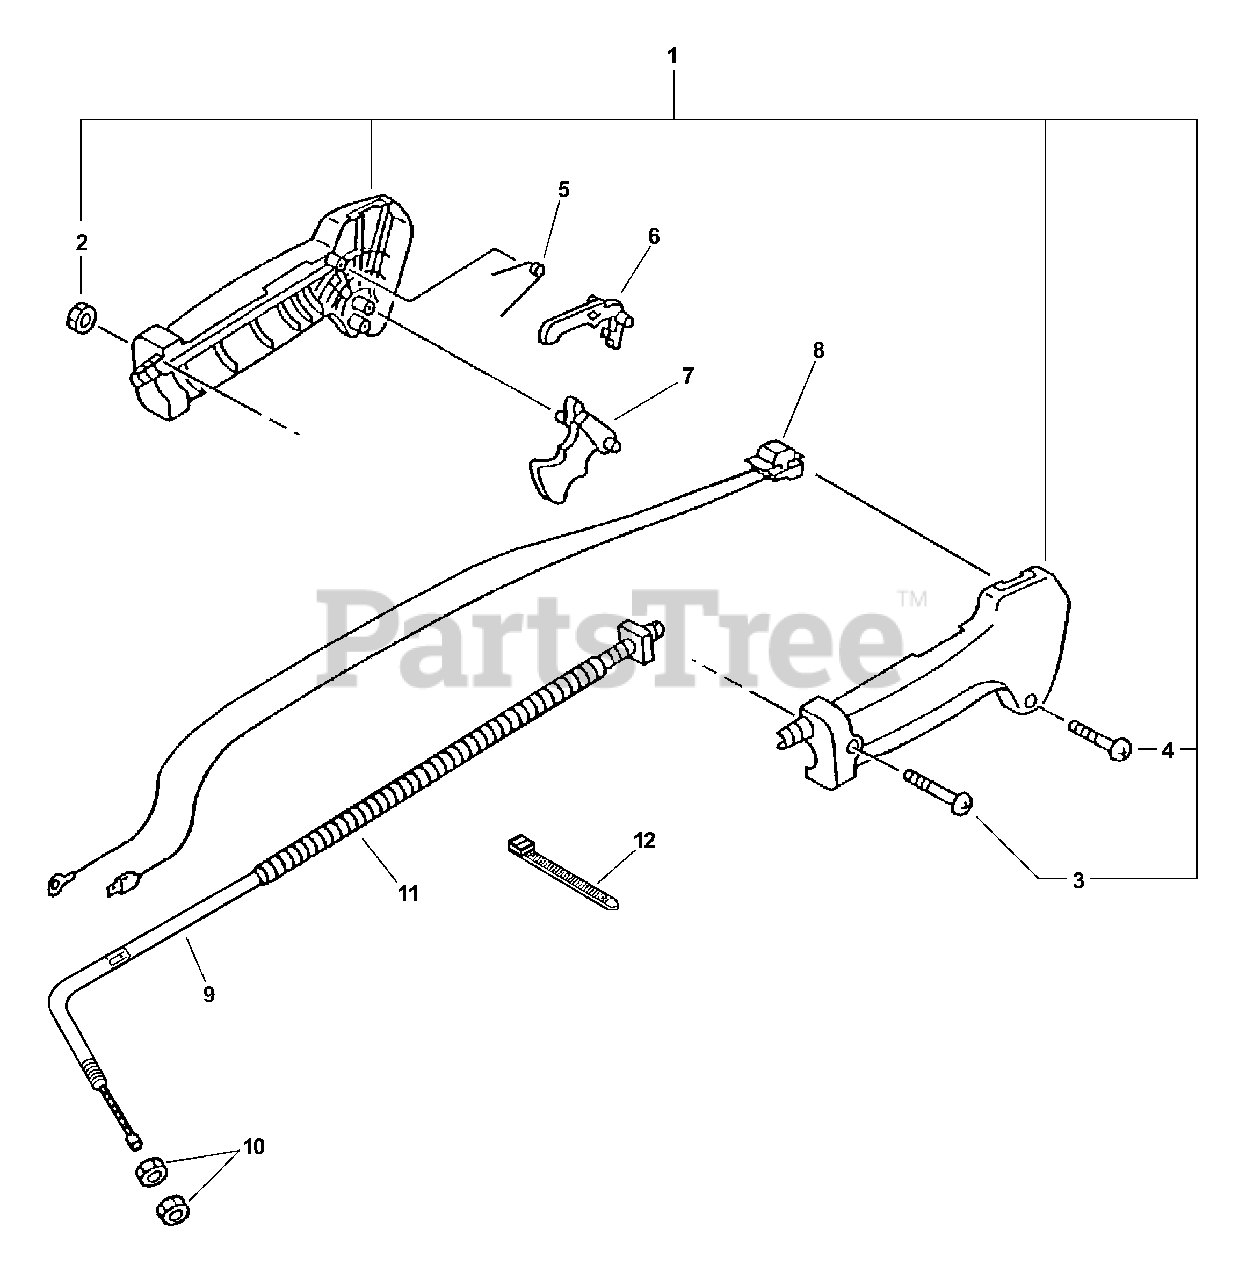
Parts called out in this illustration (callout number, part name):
1	CONTROL HANDLE KIT
2	NUT M5
3	SCREW 5×30
4	SCREW 3×25
5	SPRING, TORSION
6	LOCKOUT, THROTTLE
7	TRIGGER, THROTTLE
8	SWITCH, IGNITION
9	CABLE, THROTTLE
11	TUBE, FLEXIBLE
12	TIE, CABLE
